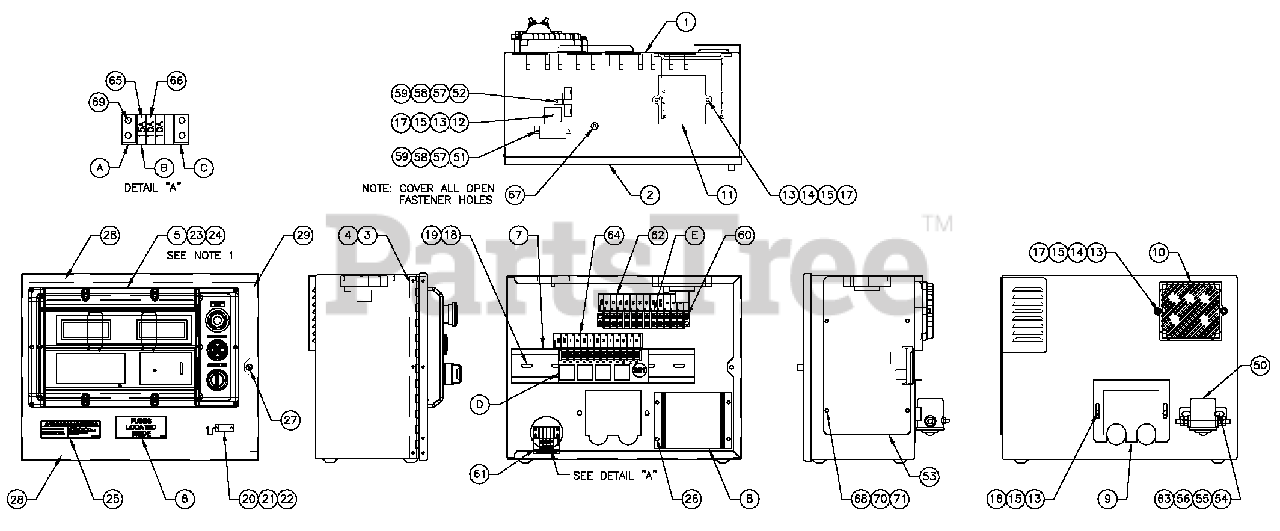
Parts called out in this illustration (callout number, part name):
1	ENCLH/G CONTROL PANEL
2	COVER CONTROL PANEL
3	HINGE CONTINUOUS H PANEL
4	RIVET POP .125X .275SS
5	ASSYPROG RAM M EDH-100
6	DECAL FUSES LOCATED INSIDE
7	RAILSNAPTRACK PCB HOLDER BULK (12" LG)
8	A SS YPC B 2AMP 12V U LB A TTC H G R
9	PLATE HARNESS CLAMP
10	A S SYPC B PW RAVRW /AM P HEADER
11	A SS YPC B BOSCH GOV DRIVER
12	DIO BRIDGE25A 600V
13	W ASHER LOCK M5
14	SCREW PPHM M 5-0.8X 30SS
15	W ASHER FLAT M5
16	SCREW HHPM M5 0 .8 X 1 2
17	NUT HEXM 5 0.8G 8 YELCHR
18	W ASHER FLAT M4
19	SCREW PHTT M 4 0 .7 X 10ZYC
20	CONN DUST CAP W/CHAIN DB9
21	W ASHER FLAT M3.5
22	SCREW PHTTM3.5 0.6X 10
23	SCREW PPHM M 4-0.7X 8 BLXO X
24	W ASHER LOCK #8 M4
25	DECAL W RNB ATT C H RG 12/24VBI
26	SCREW P H T T M 4 0 .7 X 12ZYC
27	M5 0.8 CAPTIVE PANEL KNLDHD
28	SEAL COVER 3.18 X 12.7X 382
29	SEAL COVER 3.18 X 12.7X 283
50	RELAY CONTACTOR 12VDC
53	COVER CONTROL PANEL SIDE
54	SCREW H H C 1/4 -2 0 X 3/4 G 5
55	W ASHER FLAT M6-1/4
56	W ASHER LOCK M6-1/4
57	W ASHER LOCK M3
58	NUT HEXM 3 0.5G 8 YELCHR
59	W ASHER FLAT M3
60	SCREW P HTT#6-32X 5/8ZYC
61	DECAL CPL CONTROL PANEL FUSES
62	DECAL CPL 5.4/6.8LTB3
63	NUT HEX 1/4-20 STEEL
64	DECAL CPL 5.4/6.8L RELAY BOARD
65	FUSE ATO TYPE 15 AMP (BLUE)
66	FUSE ATO TYPE 10 AMP (RED)
67	SEAL W EATHER.45"DIA
68	SCREW PPHM M 5-0.8X 12ZNC
69	SCREW P H T T #6-32X 3/8Z Y C
70	W ASHER FLAT M5
71	W ASHER LOCK M5
A	ADPTR RH SIDE WICKMANN 178.6191
B	HOLDERFUSE WICKMANN 178.6150
C	ADPTR LH SIDE WICKMANN 178.6192
D	ASSYPC B G PANEL RELAY 12VDC
E	BLOCK TERM 20A 12X 6 X 1100V
